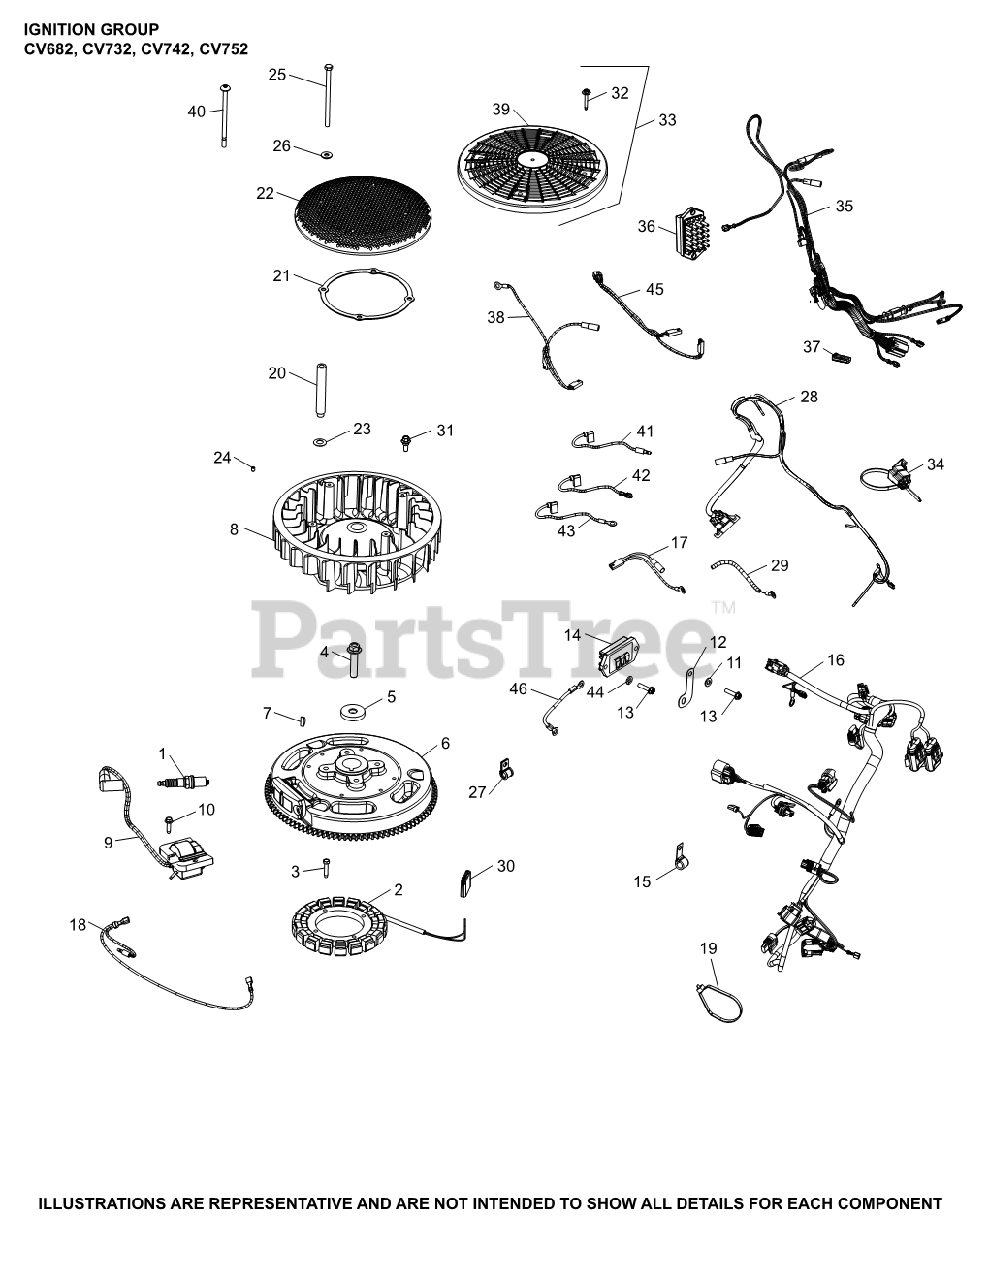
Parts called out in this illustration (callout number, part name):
1	SPARK PLUG, RFI
2	KIT, 15 / 20 AMP STATOR
3	SCREW, THREAD FORMING
4	SCREW, FLG M10X1.5X45 - (#25086361S)
5	WASHER, FLAT 13/32"
6	FLYWHEEL, ASSEMBLY
7	KEY, 3/16" X 5/8"
9	MODULE, EMC/RFI COMPLIANT
10	SCREW, THREAD FORMING
11	WASHER, FLAT 1/4" (O.D. 1/2")
13	SCREW - DISCONTINUED
14	REGULATOR/RECTIFIER
21	RING, SUPPORT
22	SCREEN, GRASS
23	WASHER, SPRING 10 MM
24	SCREW, SKT SET #10-24X1/4"
25	SCREW, CAP M6X1.0X99.5
26	WASHER, FLAT 1/4" (O.D. 5/8")
29	TUBE,RFI FLEXIBLE SLEEVE(219mm)
30	CONNECTOR
35	HARNESS, WIRING ASSEMBLY
44	WASHER, LOCK
